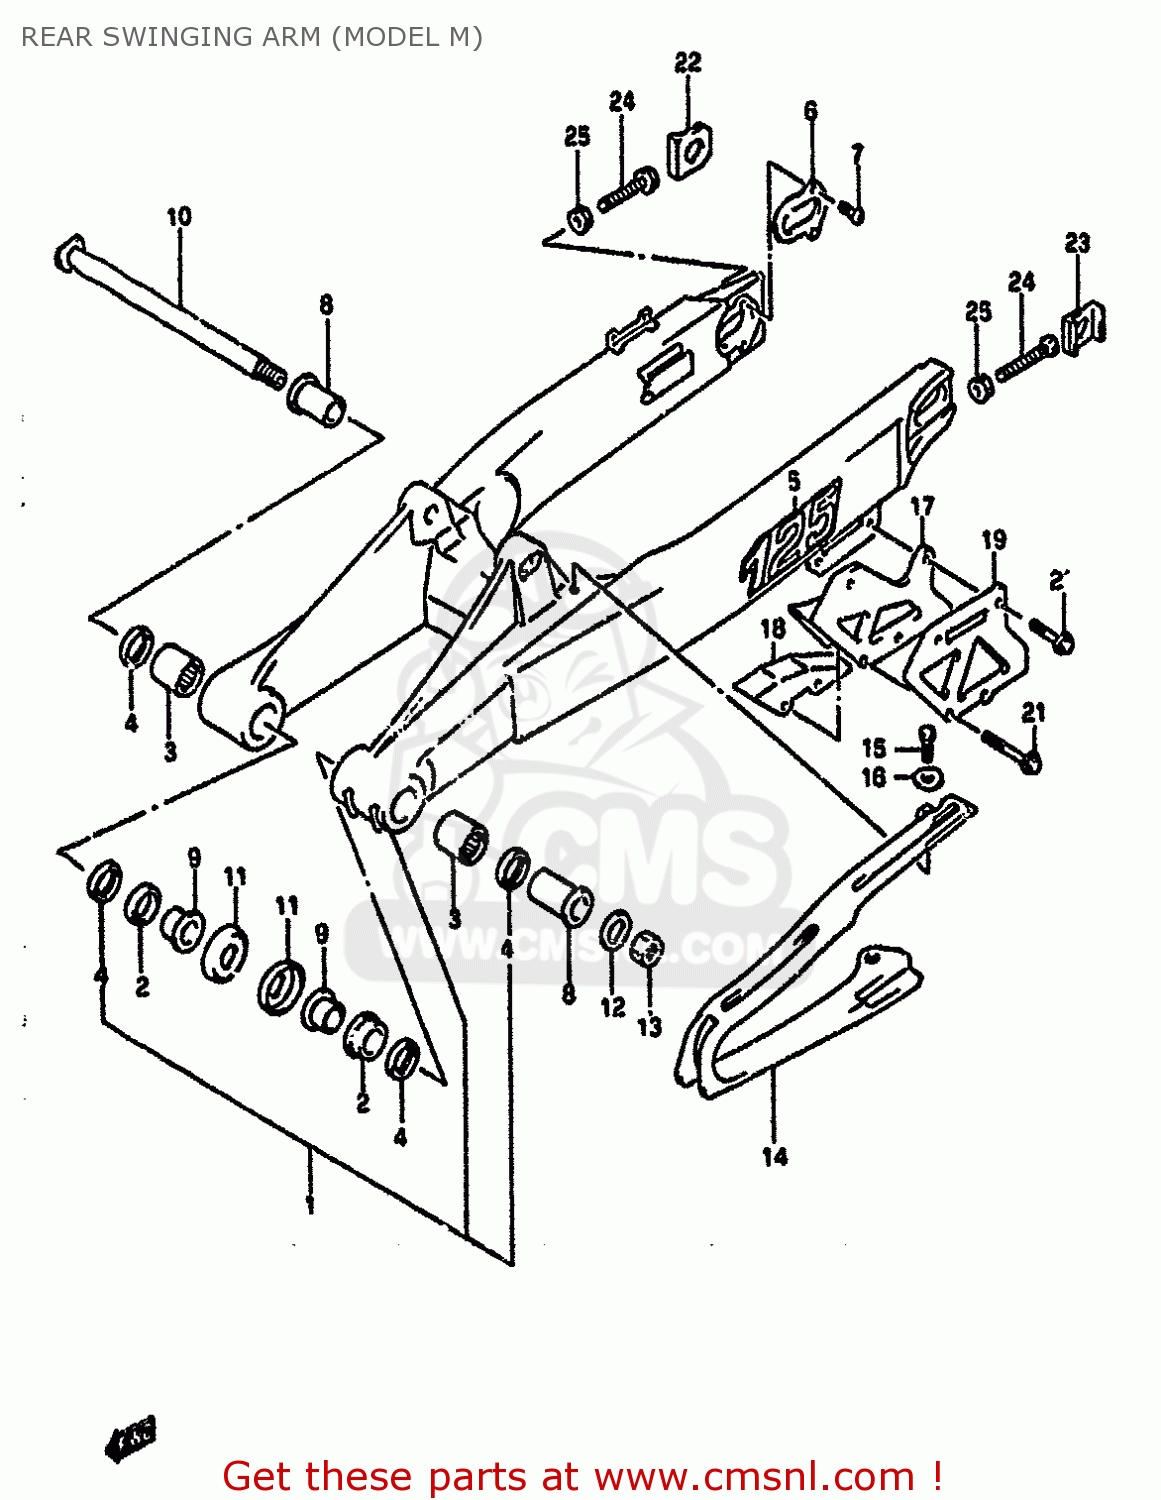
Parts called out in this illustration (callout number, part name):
1	SWING ARM ASSEMBLY,REAR
2	BUSHING,SWGARM PIVOT
3	BEARING(20X27X30)
4	OIL SEAL
5	EMBLEM,SWING ARM
6	PLATE,INNER
7	SCREW (5X8)
8	SPACER,RR SWGARM PIVOT
9	SPACER,SWGARM PIVOT INNER
10	SHAFT,RR SWINGINGARM PIVOT
11	COVER,SWGARM PIVOT
12	WASHER(14.2X24X2.3)
13	NUT
14	BUFFER,CHAIN TOUCH DEFENSE
15	BOLT
16	WASHER
17	GUIDE,CHAIN
18	DEFENSE,CHAIN GUIDE
19	PLATE,CHAIN GUIDE,OUTER
20	BOLT
21	SCREW(6X40)
22	WASHER,CHAIN ADJUSTER
23	WASHER,CHAIN ADJUSTER
24	BOLT(8X50)
25	NUT
26	NUT
27	WASHER,CHAIN ADJUSTER
28	BOLT(8X50)
29	NUT
